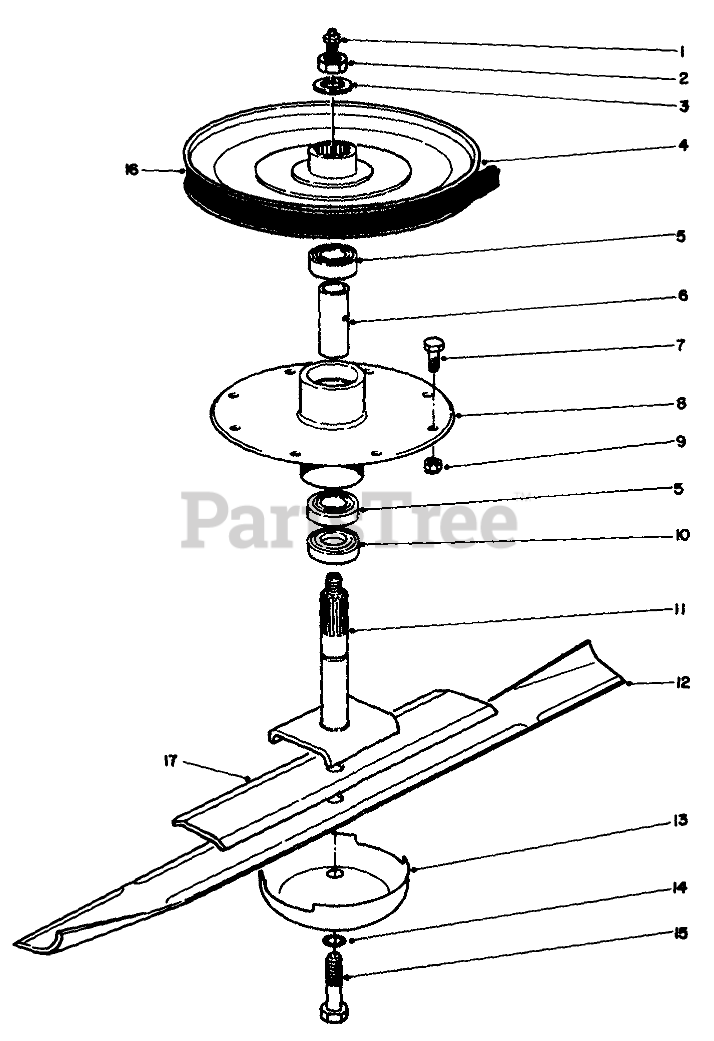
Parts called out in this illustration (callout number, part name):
1	FITTING-GREASE
2	NUT-LOCK, CONE
3	WASHER-FLAT
4	PULLEY ASM
5	BEARING-BALL
6	SPACER-BEARING
7	SCREW-HH
8	HOUSING-SPINDLE
9	NUT-LOCK, NI
10	SPACER
11	O-Ring
12	BLADE-RECYCLER
13	Cup
14	WASHER-LOCK/SP
15	SCREW-BLADE
16	V-BELT
17	BLADE SPACER ASSEMBLY
